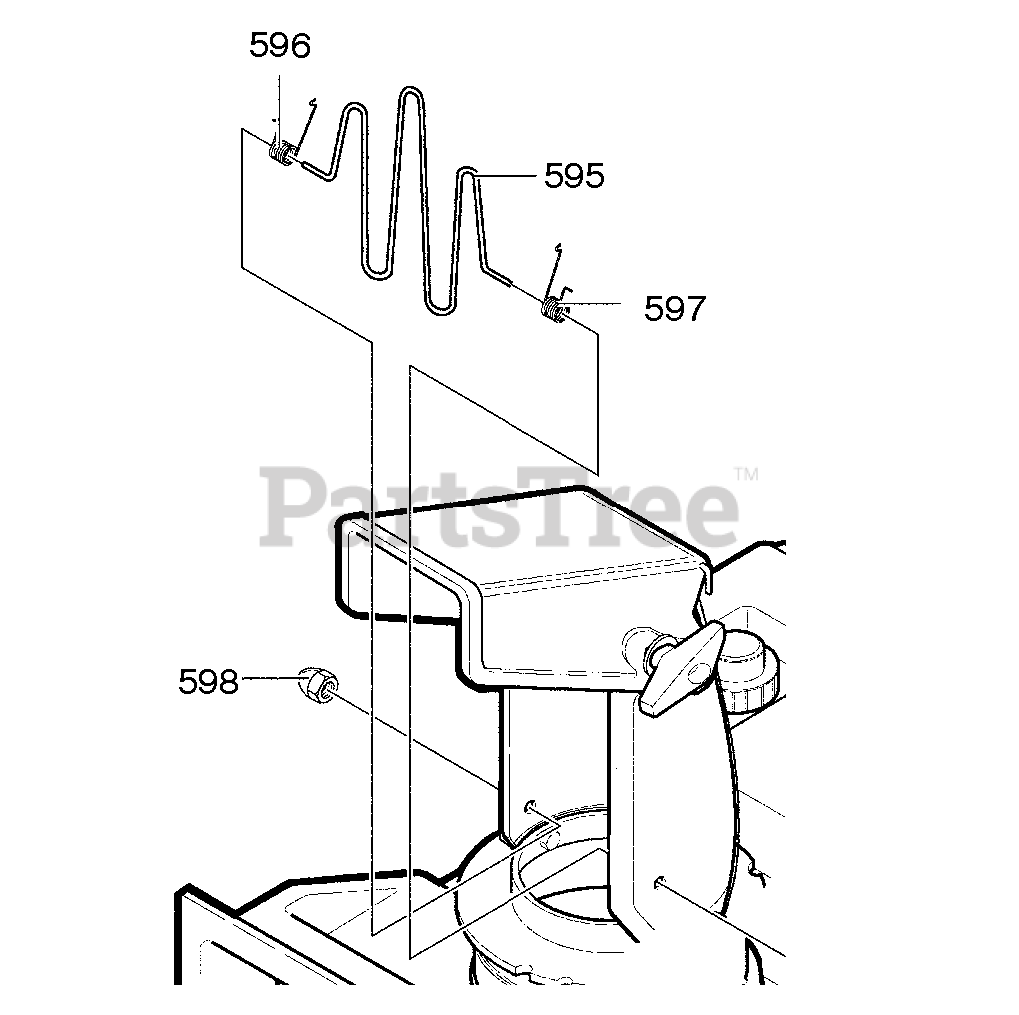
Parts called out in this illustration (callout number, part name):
595	GUARD, WIRE CHUTE
596	SPRING, TORSION
597	SPRING, TORSION
598	NUT, ACORN
